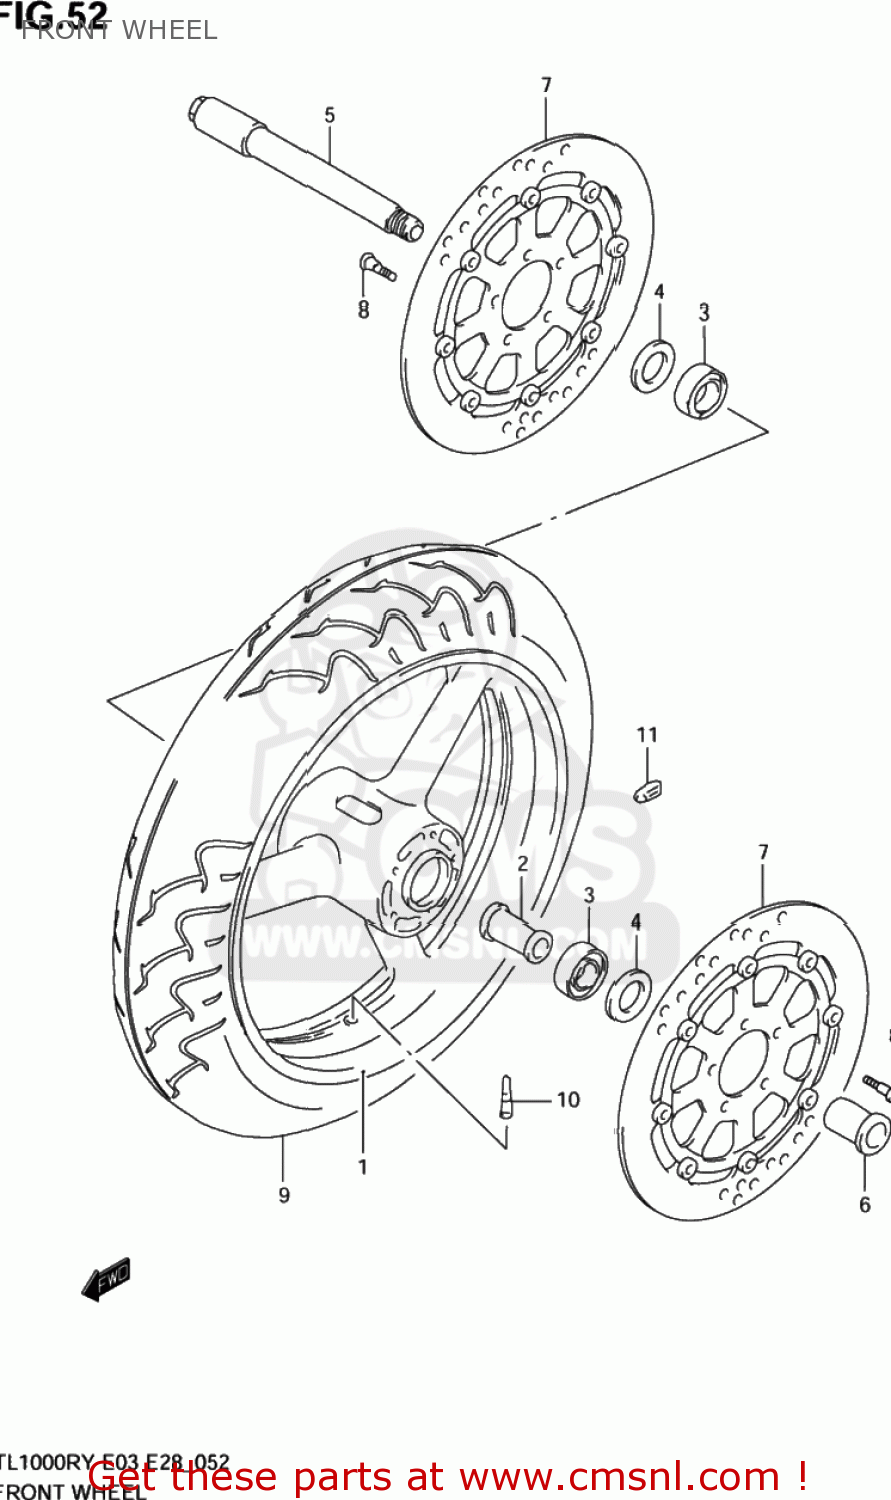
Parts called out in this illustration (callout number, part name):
1	WHEEL,FRONT (17XMT3.50)(
2	SPACER,FR HUB BEARING
3	BEARING(25X52X15)
4	SEAL,OIL(32X52X7)
5	AXLE,FR
6	NUT,FR AXLE
7	DISC,FR BRAKE
8	BOLT 8X33
9	TIRE,120/70 ZR17 (58W)
10	VALVE ASSY,WHEEL RIM(TR412)
11	BALANCER,WHEEL (10G)
